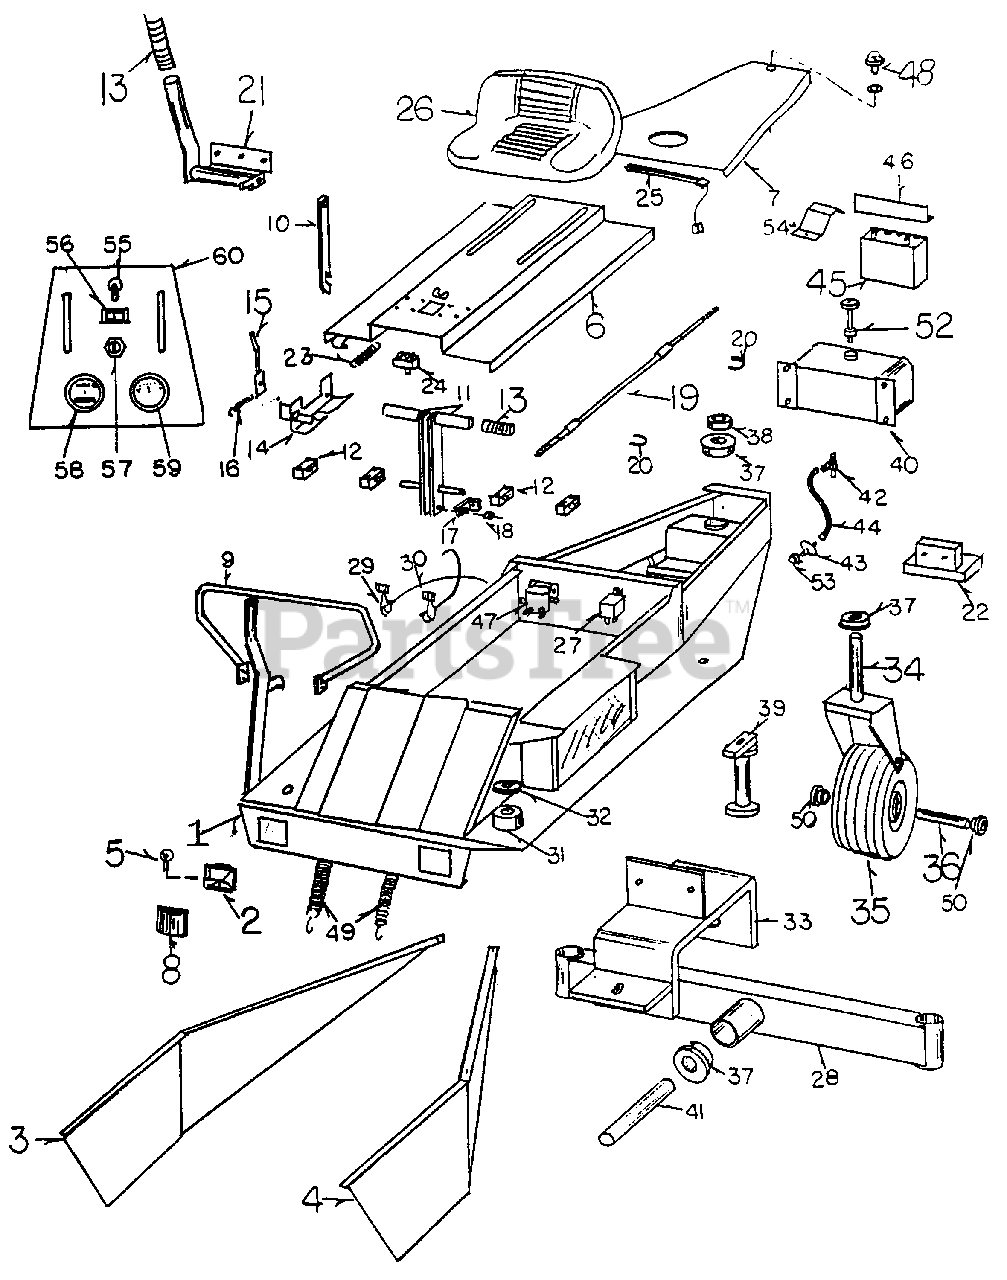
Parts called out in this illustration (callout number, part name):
1	Body
5	Bulb
8	Lens
11	Steering Lever
12	Bearing Block Steering Lever
13	Handle Grip
15	Latch, Lever Lock
16	Sprlng, Lever Lock
17	Steering cable end
18	Bushing, cable end
19	Steering cable
20	Clamp, steering cable
21	Brake lever lock
27	Electric Cluth Relay
28	Dual Tail Wheel Axle
29	Throttle Cable
30	Choke Cable
31	Rubber Body Mount
32	Body Mount Washer
33	Dual Tail Wheel Mt.
34	Tail Wheel Fork
35	Tail Wheel Assy.
36	Tail Wheel Axle
37	Tail Wheel Fork Bearing
39	Dual Tail Wheel Tube Block
42	Fuel Tank Valve
43	Fuel Filter
45	Battery
50	Tail Wheel Bearing
53	Fuel Line Clamp
54	Battery Post Protector
55	Clutch Switch
56	Light Switch
57	I6nltlon Swltch
